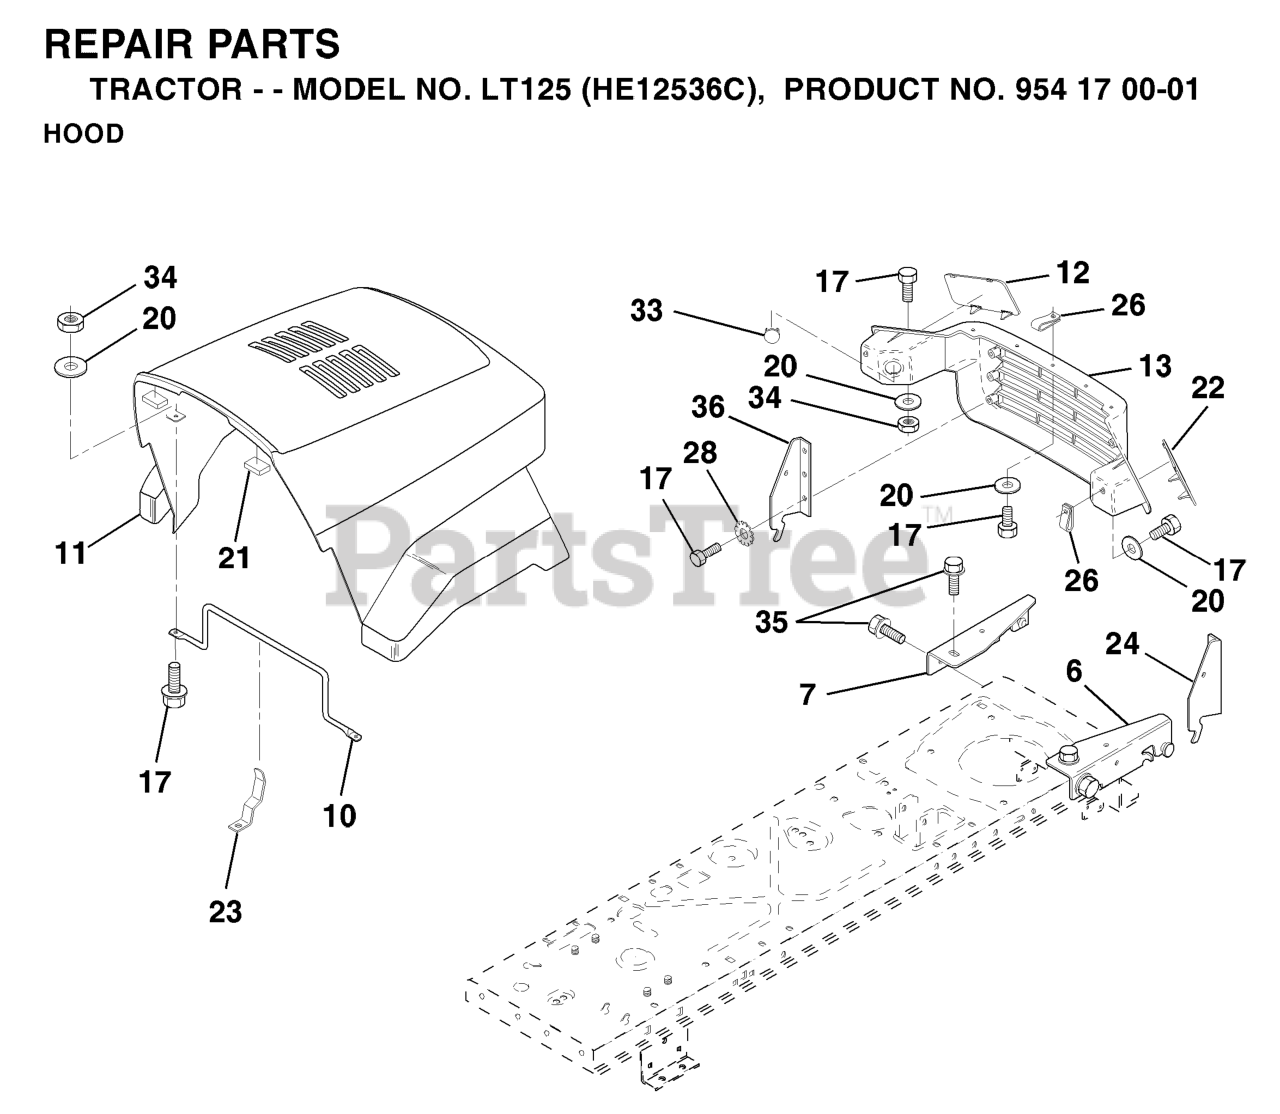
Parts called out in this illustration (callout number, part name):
6	BRACKET ASSY HOOD
7	BRACKET ASSY
10	BRACE HOOD
13	GRILL/HUSQVARNA
17	BOLT
21	BUMPER HOOD T
23	HOOD LATCH
24	BRACKET PIVOT
26	CLIP TINNERMAN
28	Washer, Lock, External Tooth 1/4
33	CVR LIGHT SOCKET
34	NUT.CROWNLOCK.1/4
35	SCREW.THDROL.5/16-18X3/4.TTY
36	BRACKET HOOD
